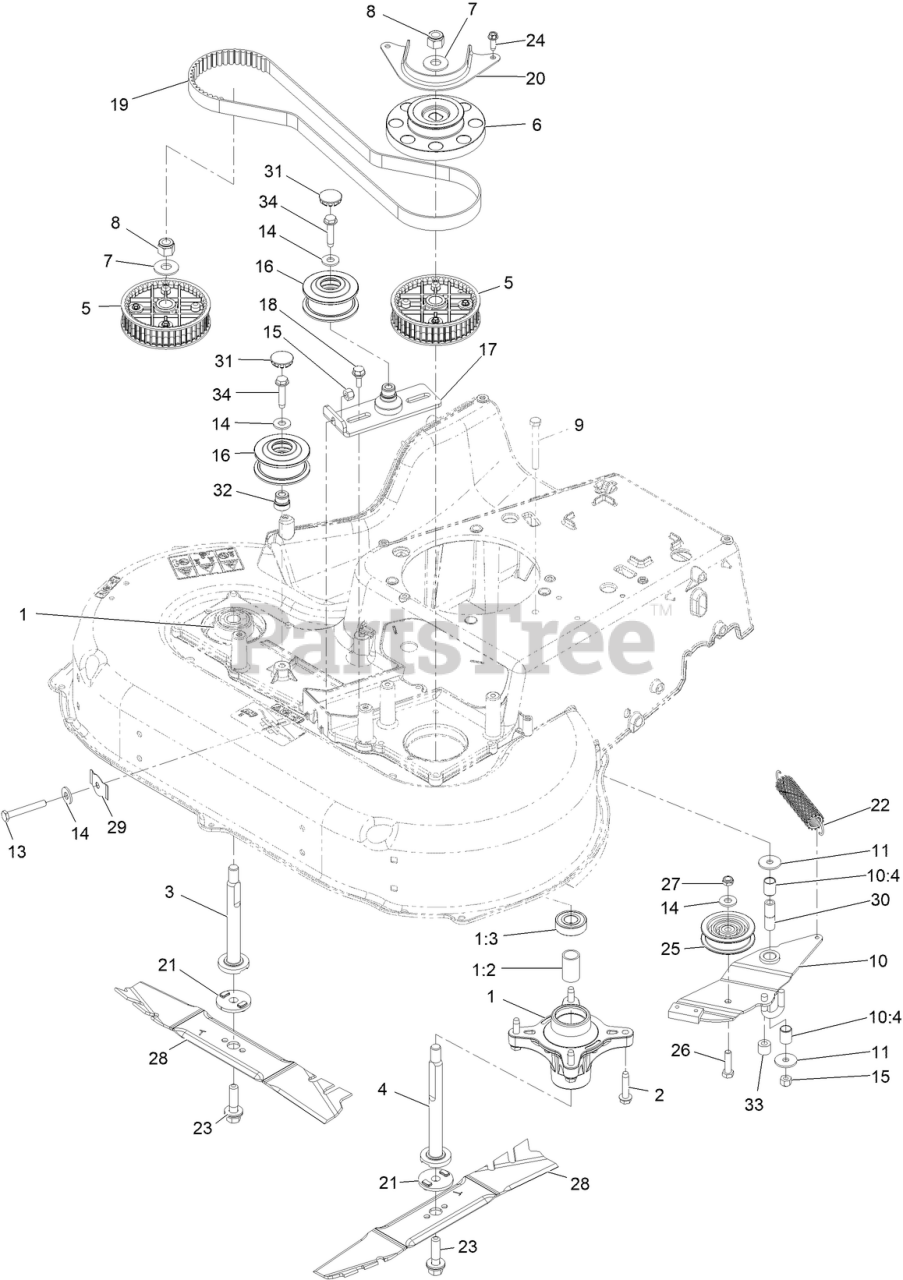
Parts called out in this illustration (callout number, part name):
1	SPINDLE ASM
1:2	SPACER
1:3	BEARING-BALL
2	SCREW-THD ROLL, HWH
3	SHAFT-SPINDLE
4	SHAFT-SPINDLE
5	SPROCKET
6	PULLEY-BRAKE, SPINDLE
7	WASHER-SPRING
8	NUT-HEX
9	SCREW-HH
10	BRAKE ARM ASM
10:4	BUSHING-SLEEVE
11	WASHER-PIVOT
13	BOLT-TAP, HH
14	WASHER-FLAT
15	NUT-LOCK, NI
16	PULLEYS AND IDLER KIT
17	BRACKET-IDLER
18	SCREW-SHOULDER,HWH
19	BELT-SYNCHRONOUS
20	GUIDE-BELT, SPINDLE
21	ADAPTER-BLADE
22	SPRING-EXTENSION, BRAKE
23	BOLT-BLADE
24	SCREW-HWHTF
25	PULLEY-IDLER
26	SCREW-HH
27	NUT-LOCK, NI
28	BLADE-ROTARY
29	SPRING-FLAT
30	SPACER-BRAKE
31	PLUG-BUTTON
32	ADAPTER-BORE
33	HOSE-COOLANT
